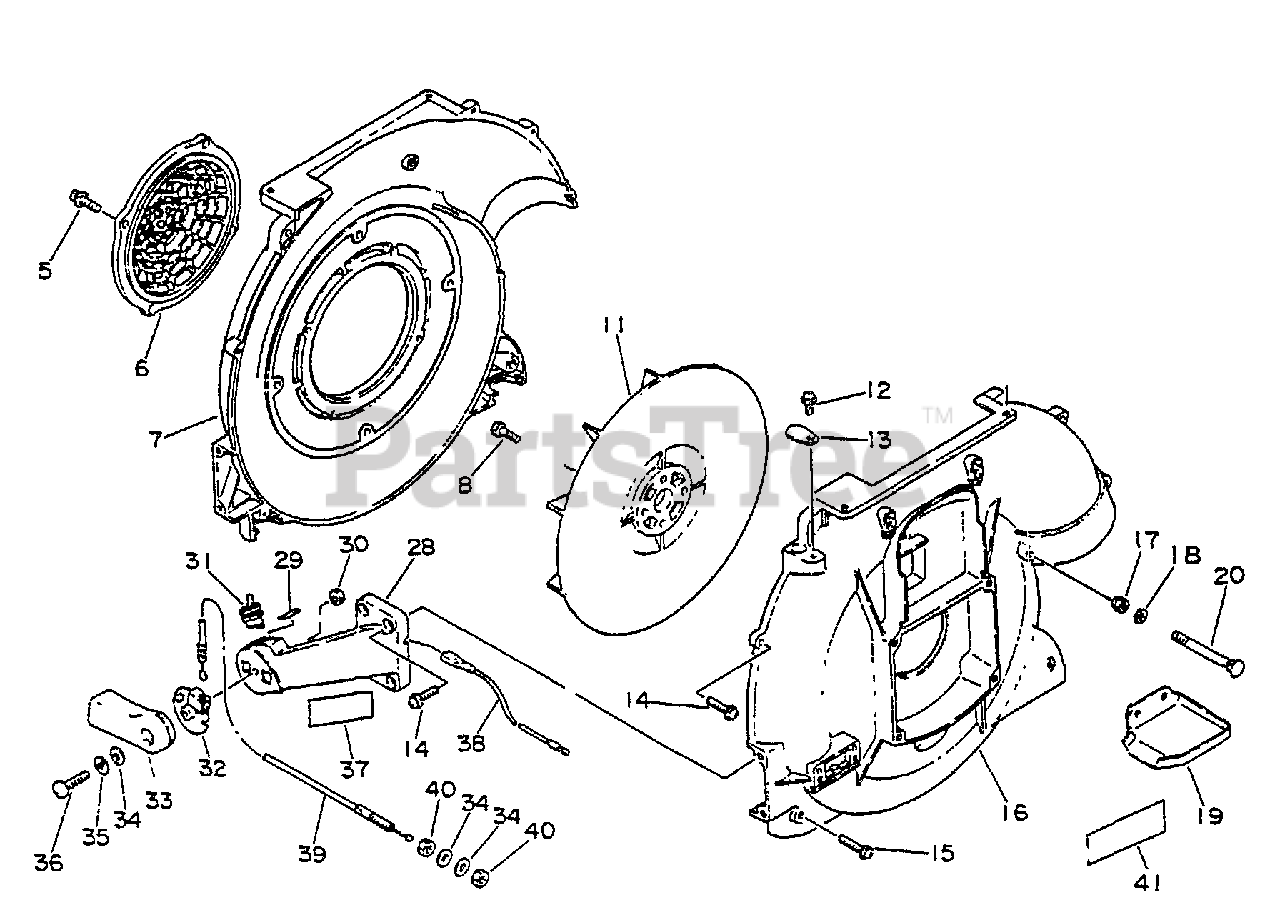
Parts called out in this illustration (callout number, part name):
5	BOLT - 6X14
6	GUARD, DEBRIS
7	COVER, FAN - INNER -- ORANGE
8	BOLT - 6X16
12	SCREW - 5X10
14	SCREW - 5X20
15	SCREW - 5X25
16	COVER, FAN - OUTER
17	NUT - 5 -- CAP
18	SCREW - 5X25
19	BRACKET, MUFFLER COVER
20	BOLT, ELBOW
28	MOUNT, THROTTLE LEVER
29	LABEL - STOP
30	LOCKNUT - 6
31	IGNITION SWITCH ASSY
33	TRIGGER, THROTTLE
34	WASHER - 6
35	LOCKWASHER - 6
36	SCREW - 6X25
37	LABEL - CAUTION
39	CABLE, THROTTLE
41	LABEL - NOISE
